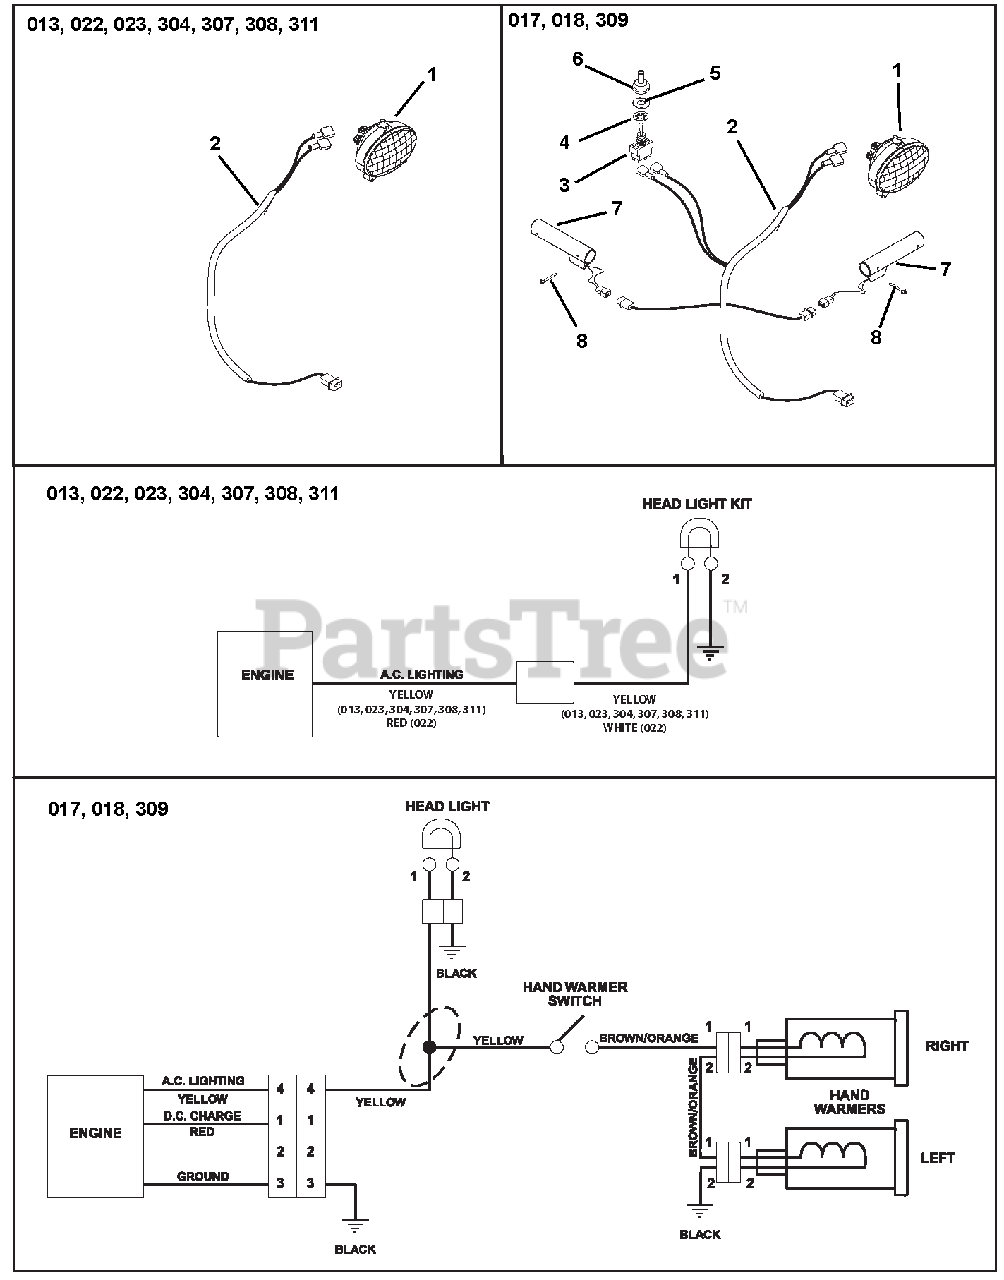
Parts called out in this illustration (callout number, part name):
1	LIGHT, HALOGEN ASSY.
1	HEAD LIGHT ASSEMBLY
2	HARNESS, HEADLIGHT 2-PIN W/GRD
2	HARNESS, LIGHT&HW, 2 PIN W/GRD
2	HARNESS, LIGHT-2 PIN W/GRD
3	SWITCH, ON/OFF
4	WSHR-LK-INT .563X.040 YWZC
5	WSHR-FL-STL .505X.875X.024 PL
6	BOOT, SWITCH
7	HEATED GRIP, MAGURA
8	RVT-POP #43 .125X.313 STL ZINC
